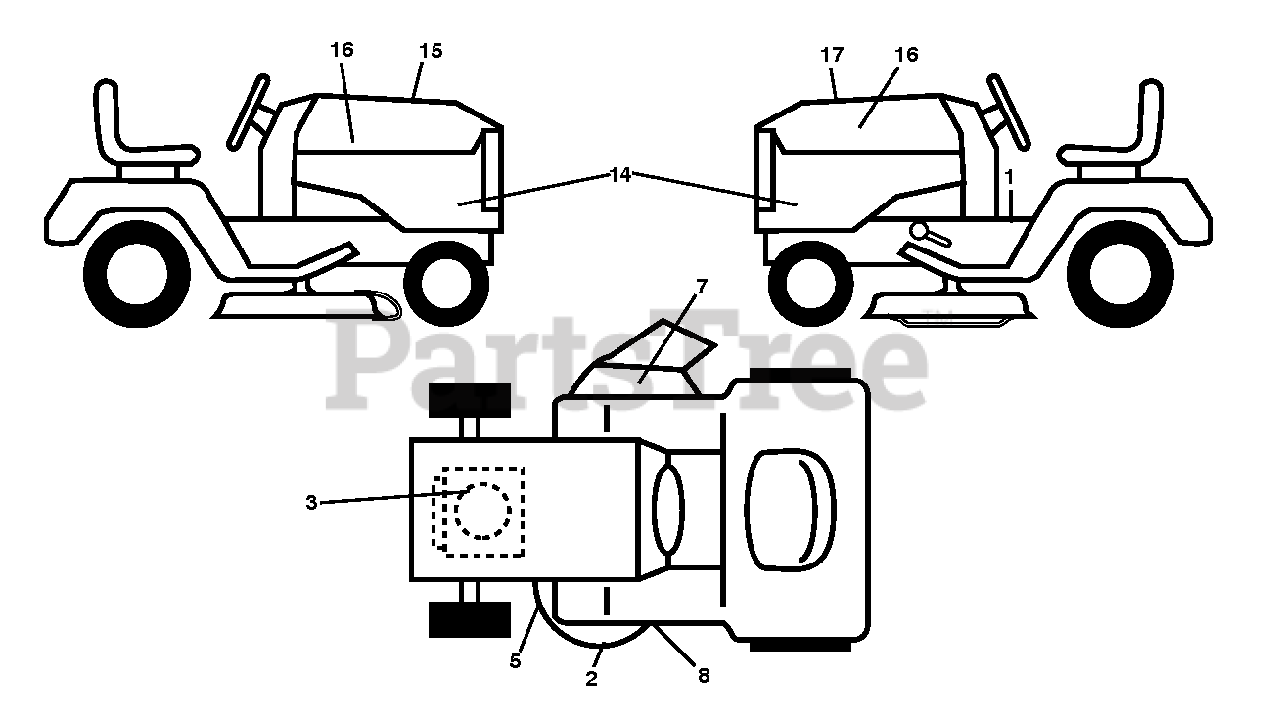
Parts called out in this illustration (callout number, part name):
1	DECAL.FENDER.WARNING.ENGLISH
3	DECAL.ENG.BS.INTK.24HP.382016
5	DECAL.MOWER.CAUTION.TENSION.AR
7	DECAL, DECK DEFLECTOR, WARNING
8	DECAL.MOWER.SCH.48/54.PREM
14	DECAL SIDE PANEL
15	DECAL.WARNING.CUST.RESP.E85.
16	Decal, WB 178MM 15 Husqvarna NEWBRAN
17	Decal, Replacement BSM44 INTK TLW
